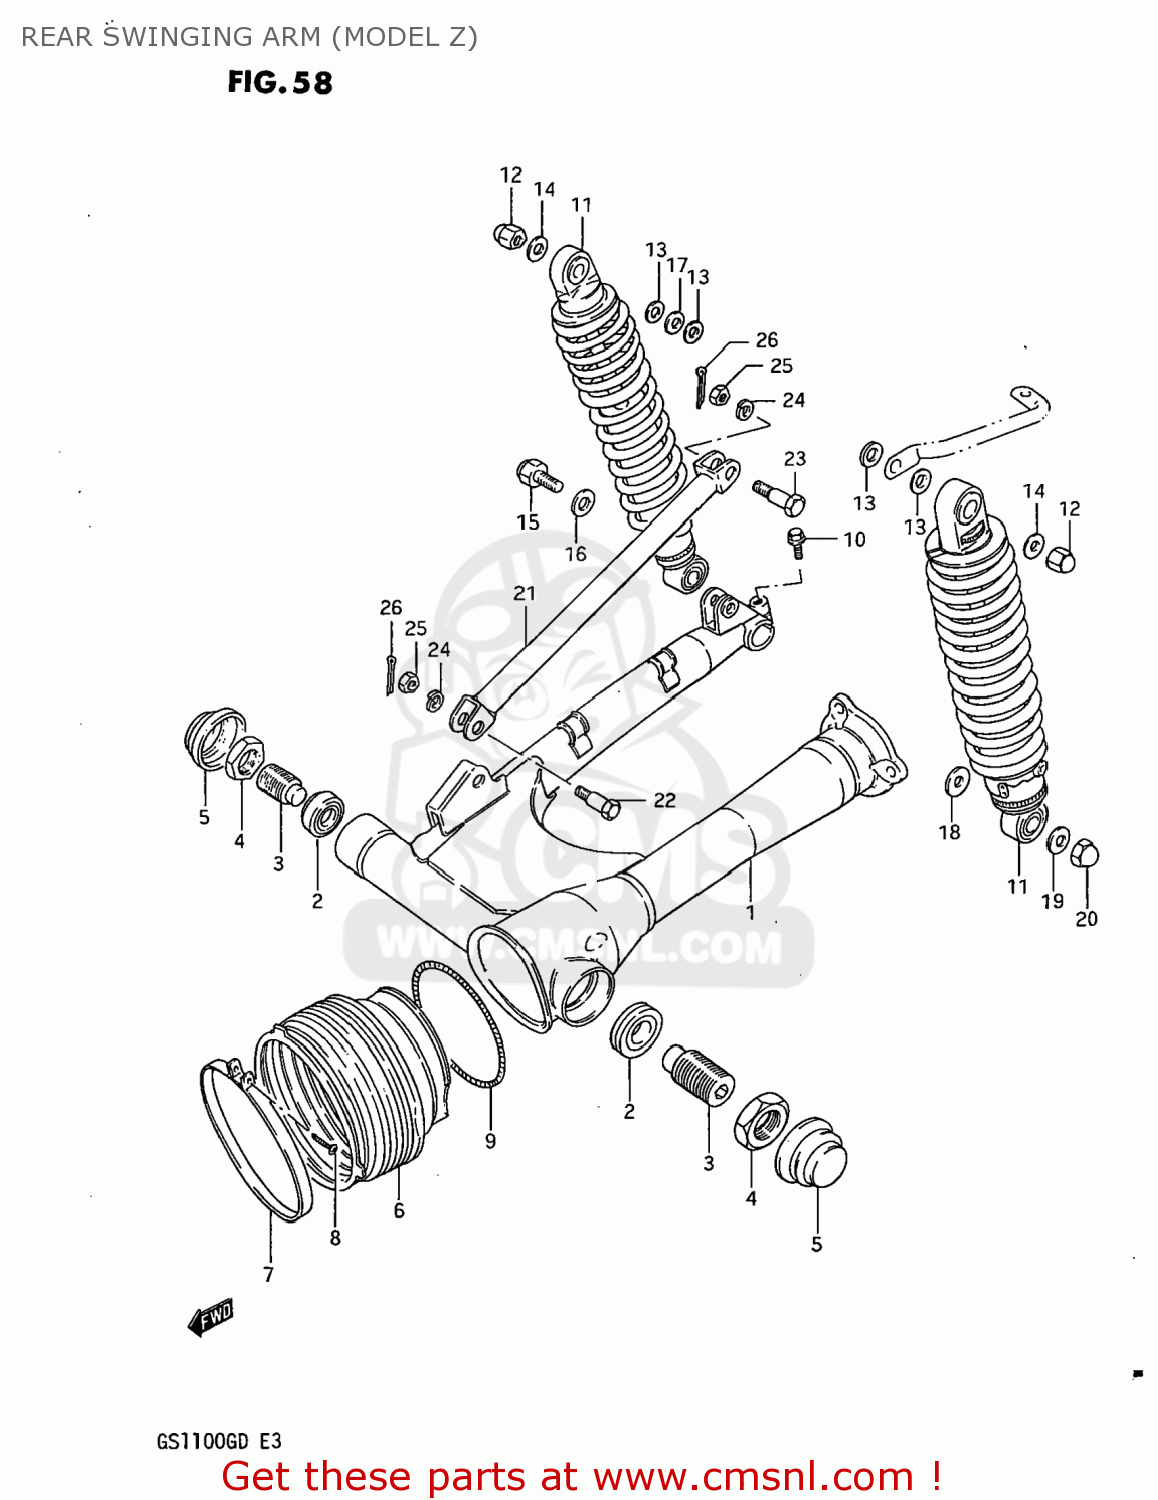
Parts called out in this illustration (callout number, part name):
1	SWING ARM SET,REAR (B
2	BEARING(17X40X13.25)
3	BOLT,REAR SWING ARM PIVOT
4	NUT
5	CAP,REAR SWING ARM PIVOT
6	BOOT,PROPELLER SHAFT
7	CLAMP
8	SCREW 4X25
9	SPRING,PROPELLER SHAFT
10	BOLT
11	ABSORBER ASSEMBLY,REAR SHOCK
12	NUT
13	WASHER
14	WASHER
15	BOLT 12X33
16	WASHER (12.5X24X1.6)
17	WASHER (12.5X24X3.2)
18	WASHER
19	WASHER
20	NUT, LOWER LH
21	TORQUE LINK,REAR
22	BOLT
23	BOLT(10X39)
24	WASHER
25	NUT
26	PIN 20X20
